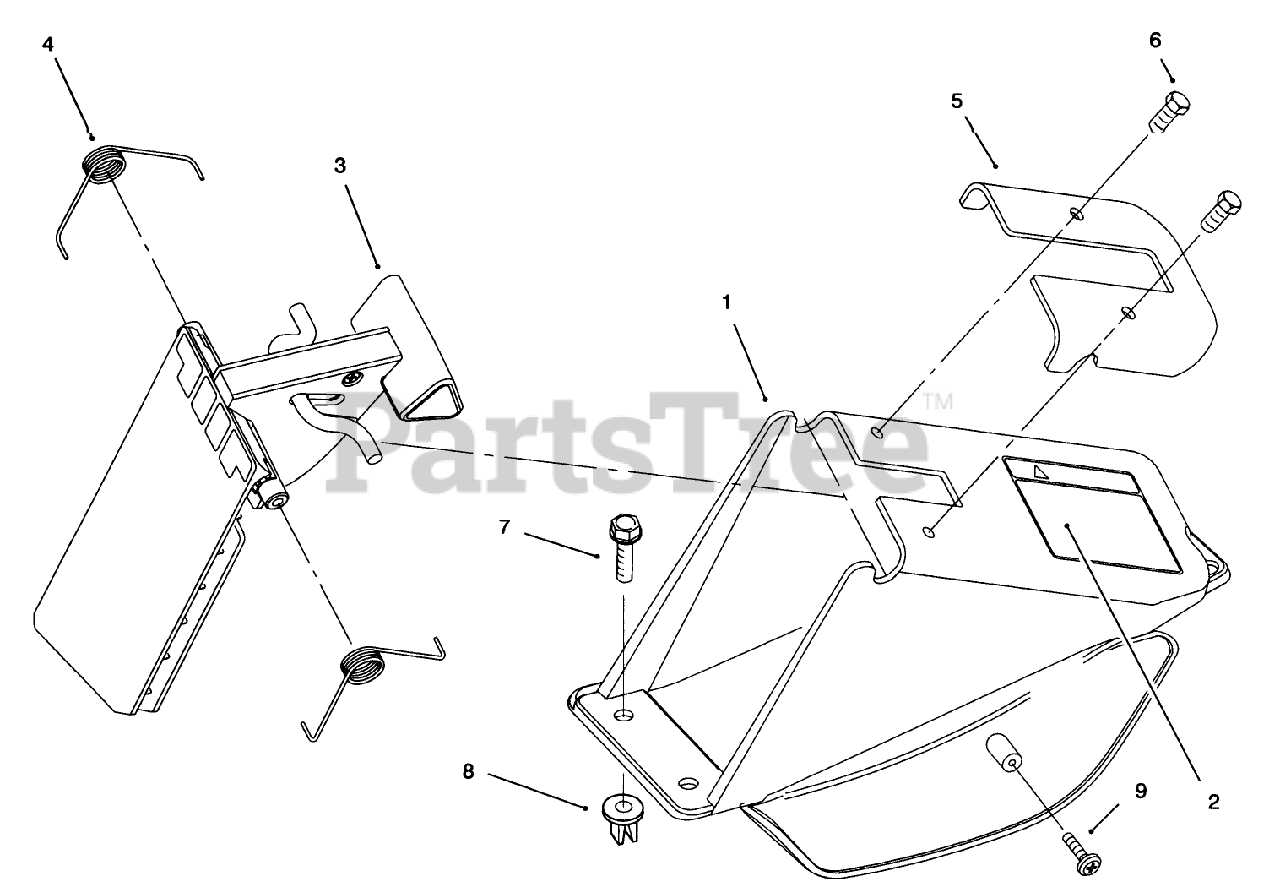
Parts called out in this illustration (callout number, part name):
1	CHUTE - DISCHARGE
2	DECAL - CAUTION DOOR
3	ASM - DISCHARGE DOOR
4	SPRING-DOOR, RH
5	Plate-Discharge
6	SCREW-PLASTITE
7	SCREW-HWH
8	NUT - CLIP
9	SCREW-PPH
